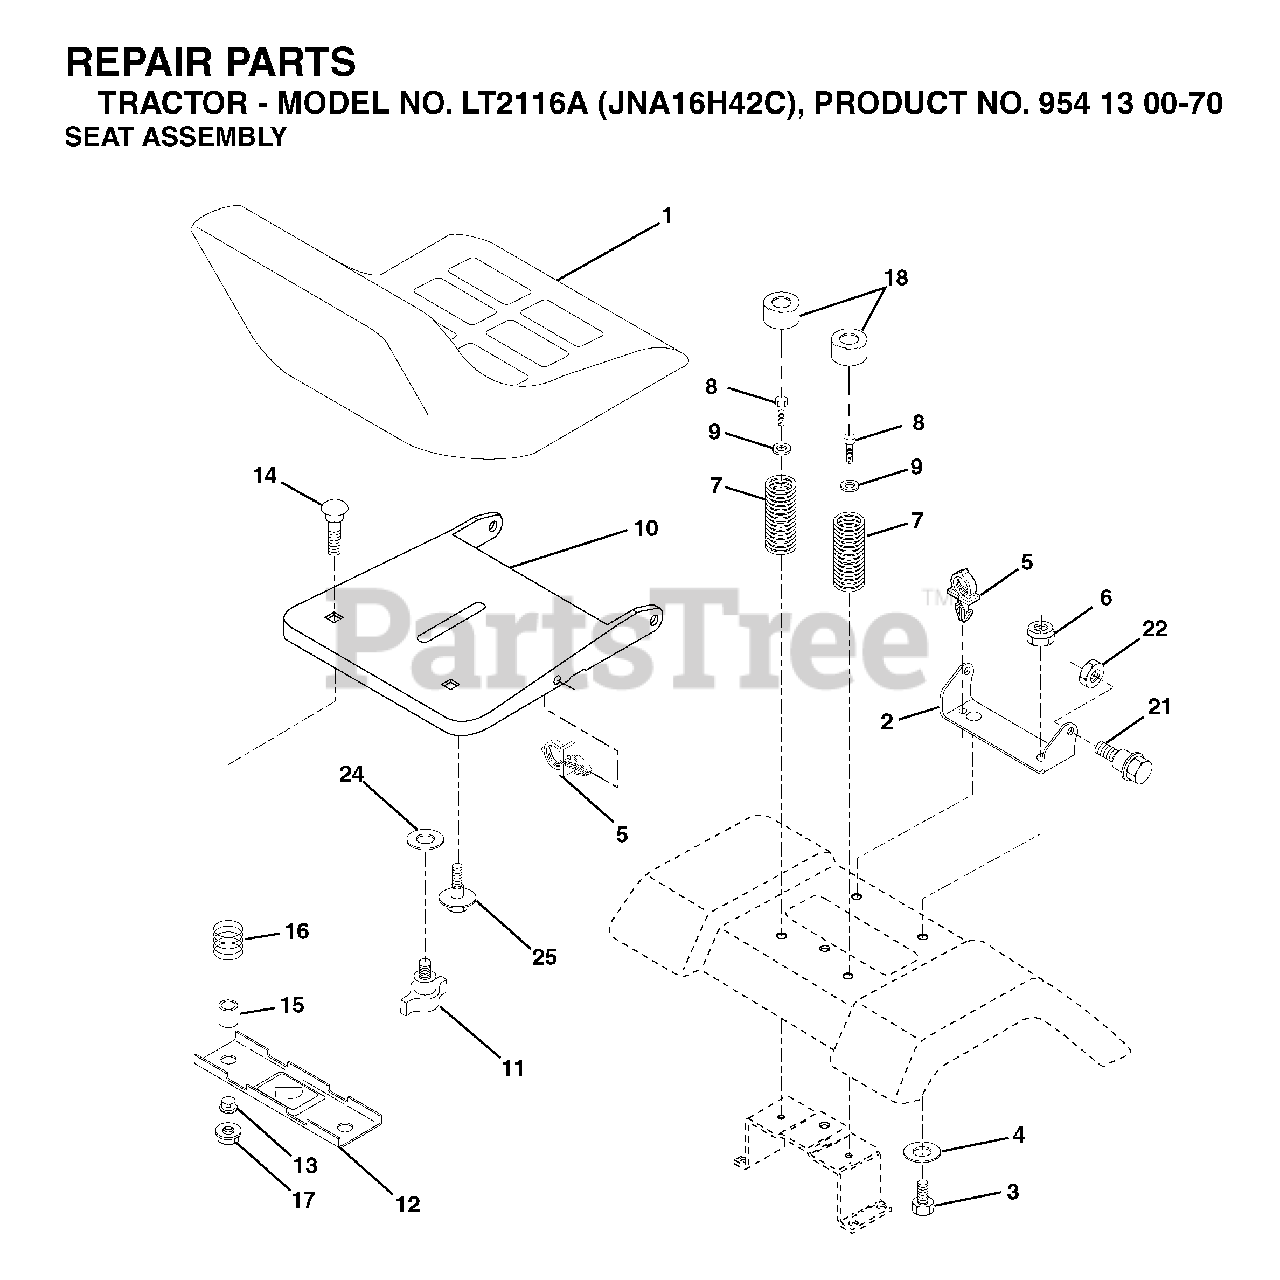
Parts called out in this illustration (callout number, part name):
2	SEAT PIVOT BRKT
4	WASHER PM
5	PUSH CLIP
6	NUT
7	SPRING COMPRESSION
8	SCREW 3/8-16X1
9	WASHER
10	PAN SEAT
11	KNOB.SEAT.ADJ.WINGNUT
12	BRKT SWITCH
14	BOLT.ROUND.HEAD.SQUARE.NECK
15	SPACER SPLIT
16	SPRING COMPRESSED
17	NUT T
18	CAP SPRING
21	BOLT.SHOULDER.5/16-18
22	NUT.71038.31-18.HEX.NYLOCK
25	BOLT,SHOULD
